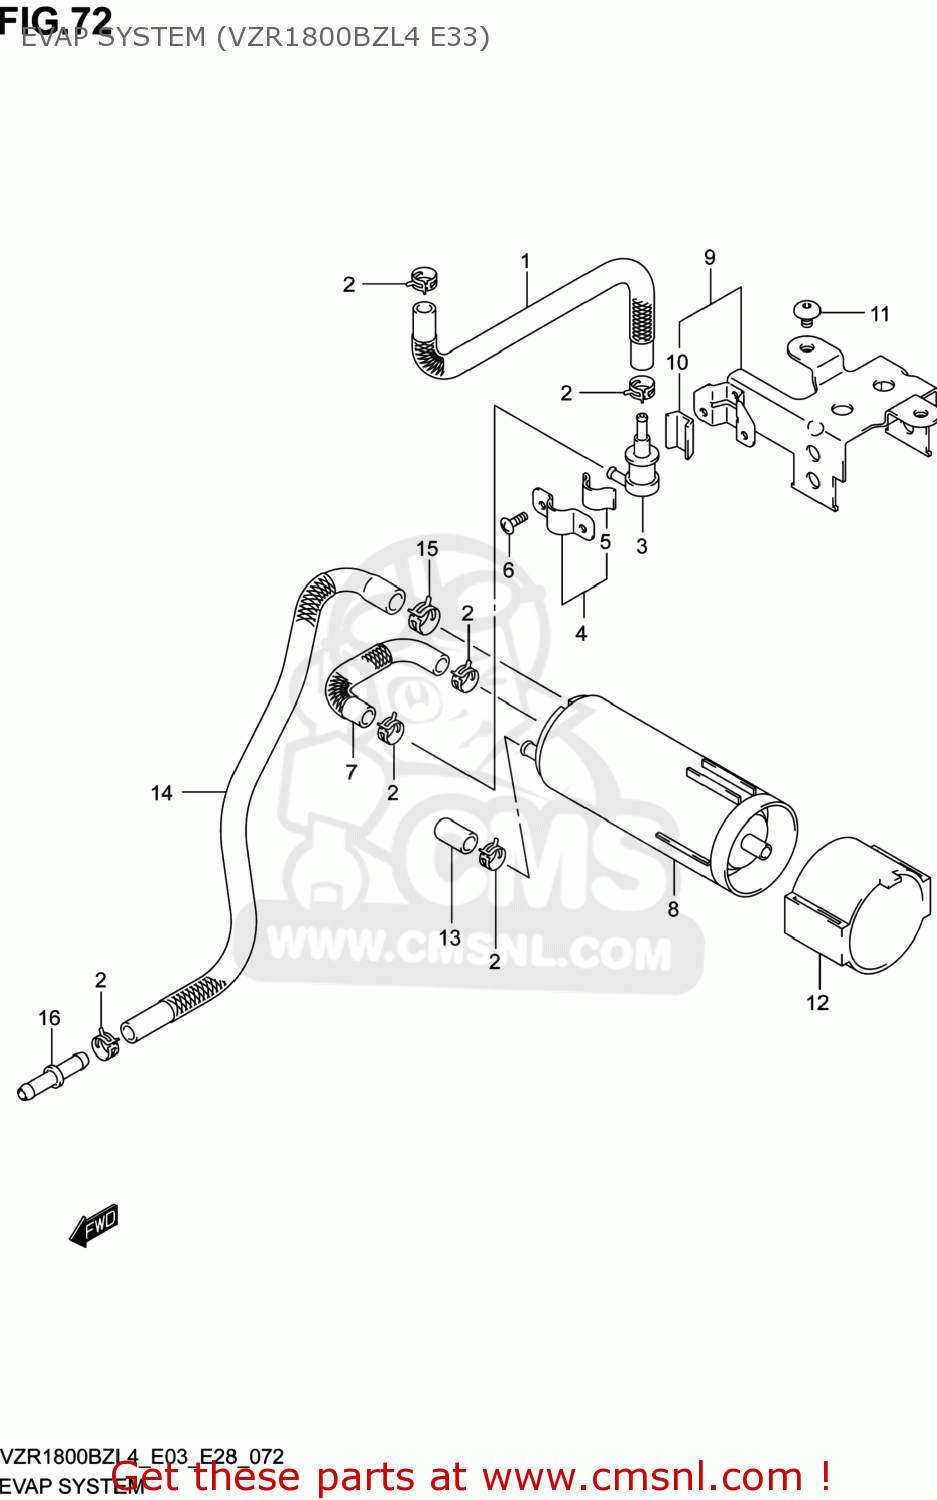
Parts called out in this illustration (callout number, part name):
1	HOSE,TANK & BREATHER VALVE
2	CLIP
3	VALVE,FUEL TANK BREATHER
4	PLATE,FUEL TANK BREATHER NO.2
5	CUSHION
6	SCREW
7	HOSE,BREATHER VALVE & CANISTER
8	CANISTER ASSY,CHARCOAL
9	BRACKET,CANISTER
10	CUSHION
11	SCREW(6X12)
12	CUSHION,CANISTER
13	CAP
14	HOSE,CSTR PURGE
15	CLIP
16	JOINT
